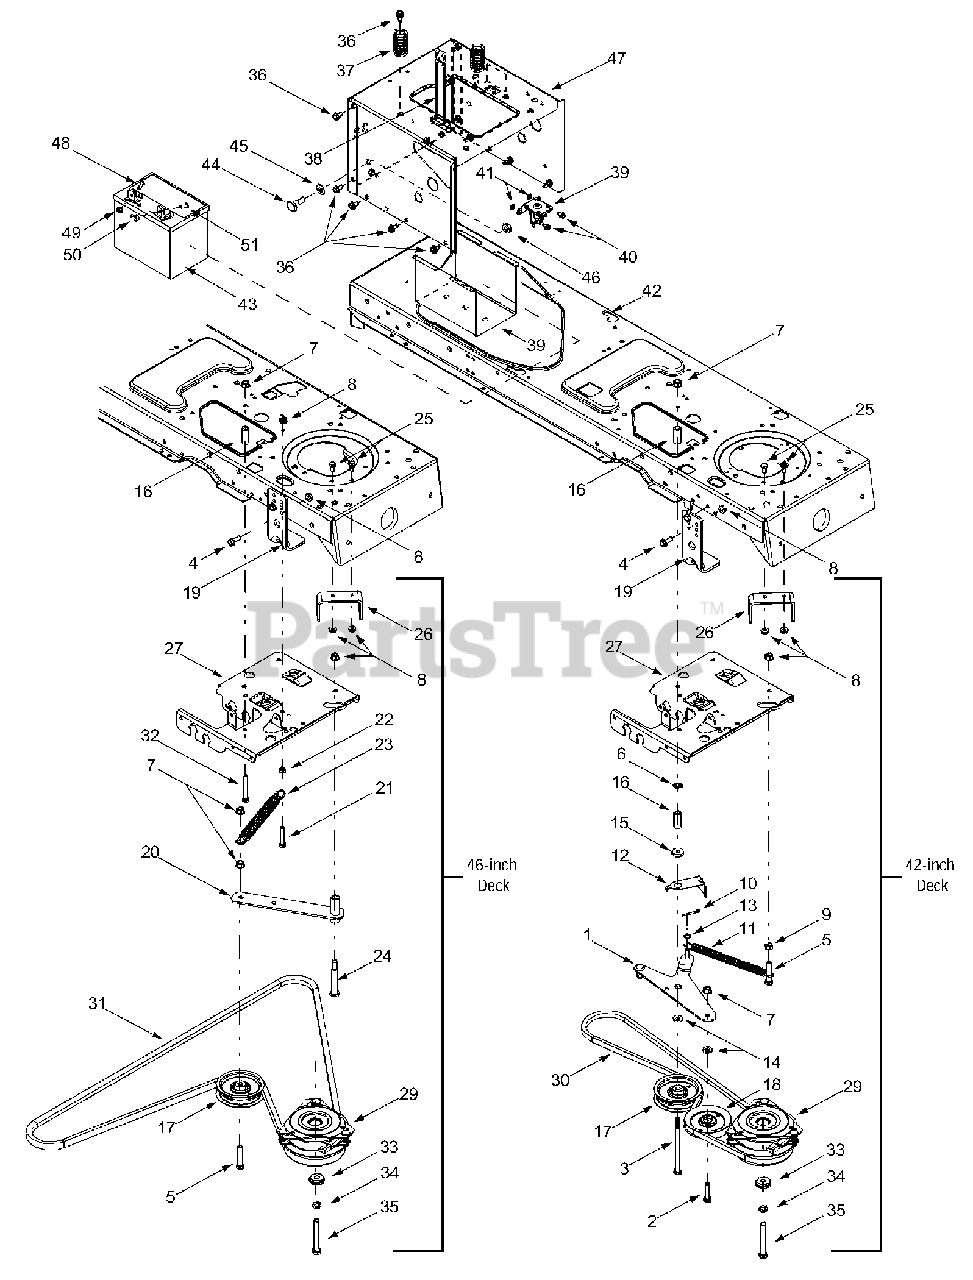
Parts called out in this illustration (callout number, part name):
3	Hex Cap Screw, 3/8-16 x 5.5
4	Hex Head Washer Screw, 5/16-18 x .875
5	Hex Cap Screw, 3/8-16 x 2.0
6	Push Nut, 3/8
7	Flange Lock Nut, 3/8-16
8	Flange Lock Nut, 5/16-18
9	Hex Nut, 3/8-16
10	Cotter Pin, 1/8 x 1.25
11	Extension Spring, .62 x 6.12
12	Belt Guard
13	Flat Washer, .385 x .62 x .063
14	Flat Washer, .407 x .812 x .135
15	Shoulder Spacer, .380
16	Spacer, 3/8 x 1.54
17	Idler Pulley, 3.5
18	Idler Pulley, 4.0
22	Hex Nut, 5/16-18
23	Extension Spring, .62 x 5.62
24	Shoulder Screw, 1/2 x 2.5
25	Hex Cap Screw, 5/16-18 x .625
30	PTO Belt (Models w/ 42-inch deck)
31	PTO Belt (Models w/ 46-inch deck)
32	Hex Cap Screw, 3/8-16 x 2.5
33	Shoulder Spacer, 1.38 x .445 x .36
34	Lock Washer, 7/16
35	Hex Cap Screw, 7/16-20 x 3.25 (Grade 5)
36	Self Tapping Screw, 5/16-18 x .625
37	Compression Spring, 1.28 x 3.5
38	Battery Strap
39	Solenoid, 12-Volt, 100 Amp
40	Self Tapping Screw, 1/4-20 x .5
41	Lock Washer, 1/4
44	Shoulder Screw, .625 x .5, 7/16-20
45	Bell Washer, .45 x 1.0 x .062
46	Flange Lock Nut, 7/16-20
49	Hex Sems Nut, 1/4-20
50	Wing Nut, 1/4-20
51	Shoulder Screw, 1/4-20, .25 x .15
